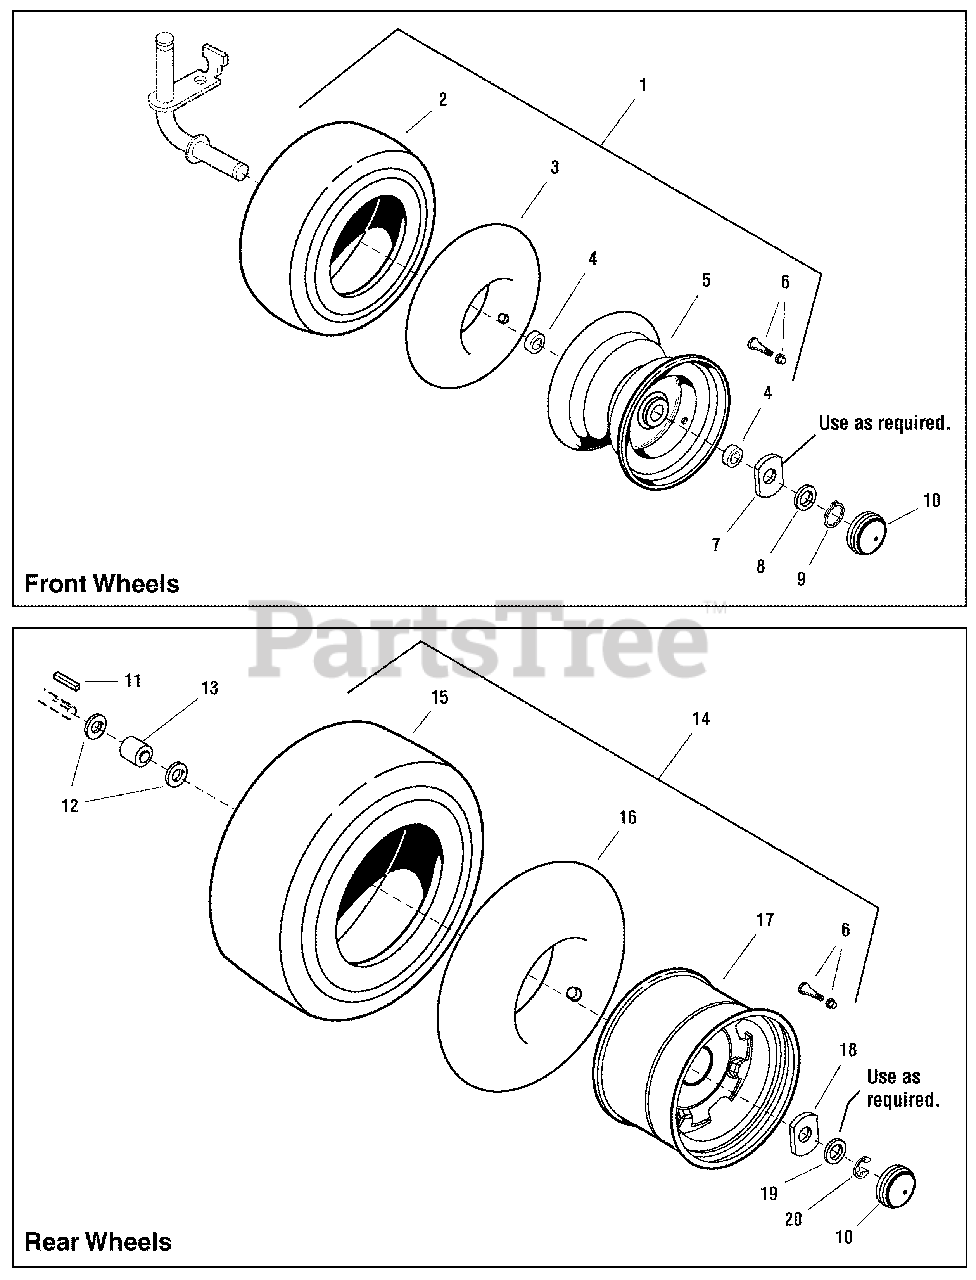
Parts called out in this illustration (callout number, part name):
1	WHEEL & TIRE ASSEMBLY, Front
2	TIRE, 15 x 6, Super Turf
3	TUBE, Tire, Front, 4.10/3.50
4	BEARING, Ball
5	WHEEL, 4-1/2" x 6"
6	VALVE STEM & CAP ASSEMBLY
7	WASHER, Special, (As Required)
8	WASHER, 1, (As Required)
9	RING, Retaining, External #98
10	CAP, Hub, Gray
11	KEY, Parellel, 3/16 x 3/16 x 1-1/2
12	WASHER, 3/4
13	SPACER
14	WHEEL & TIRE ASSEMBLY
15	TIRE, 20 x 10, 8 Super Turf
16	TUBE, Tire, 20 x 8, Rear
17	WHEEL, 7 x 7.96, W/ 3/4 OD Shaft
18	WASHER, Special
19	WASHER, 3/4
20	RING, "E" External
